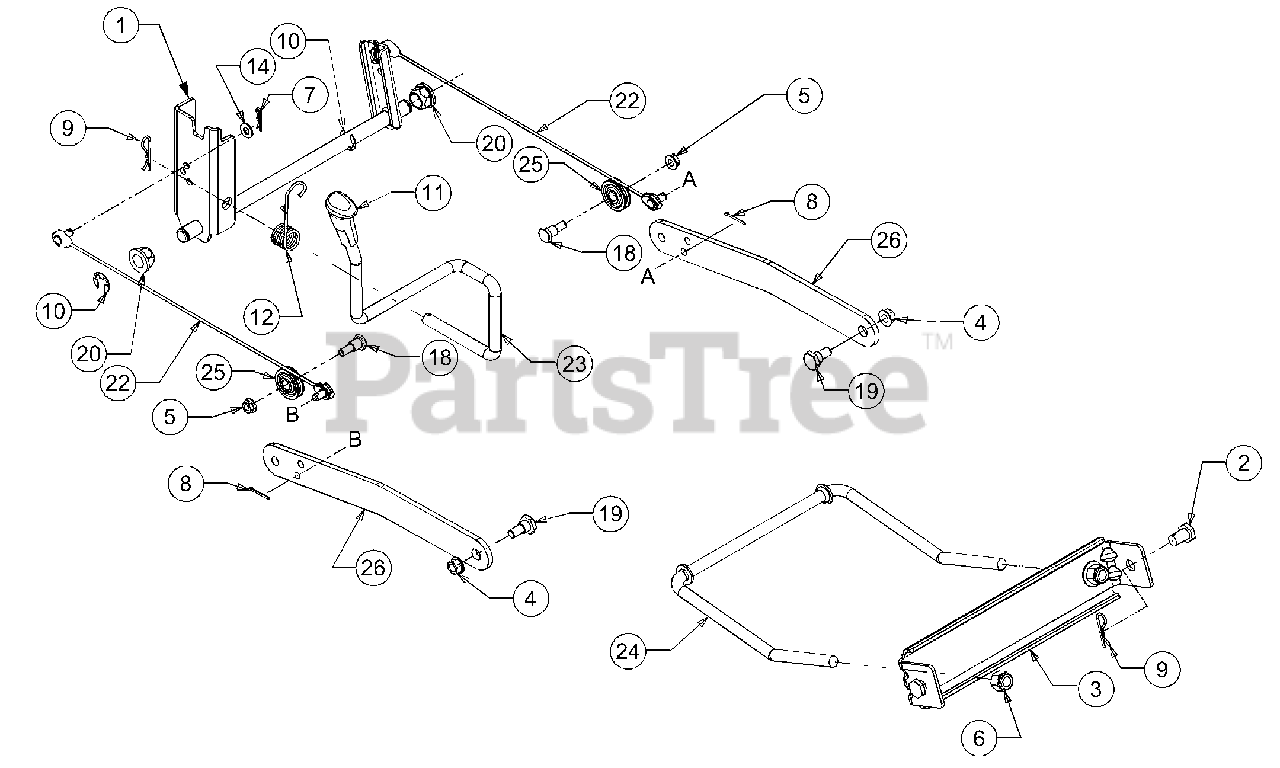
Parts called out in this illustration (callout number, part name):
1	Shaft Assembly, Lift
2	Pin, Clevis, .50 Dia x .78 Lg
4	Nut, Nylon Lock, 3/8-16
5	Nut, Nylon Lock, 5/16-18, Gr5
6	Nut, Hex Lock, 1/2-13, Gr8, Nylon
7	Pin, Cotter, .072 Dia. x 1.13 Lg
8	Pin, Cotter, 3/32, 1.0
9	Pin, Click, .092 x 1.64 Lg
10	E-ring, .625 Dia. Shaft
11	Grip, Handle
12	Spring, Torsion
18	Screw, Hex Cap, 5/16-18x .620 Gr2
19	Shoulder Screw, 3/8-16
20	Bearing, Hex Flange
22	Cable, Lift, 16.16 Lg
23	Handle, Lift
24	Rod, Deck, Front Adjustment .5" Dia
25	Pulley, Roller
